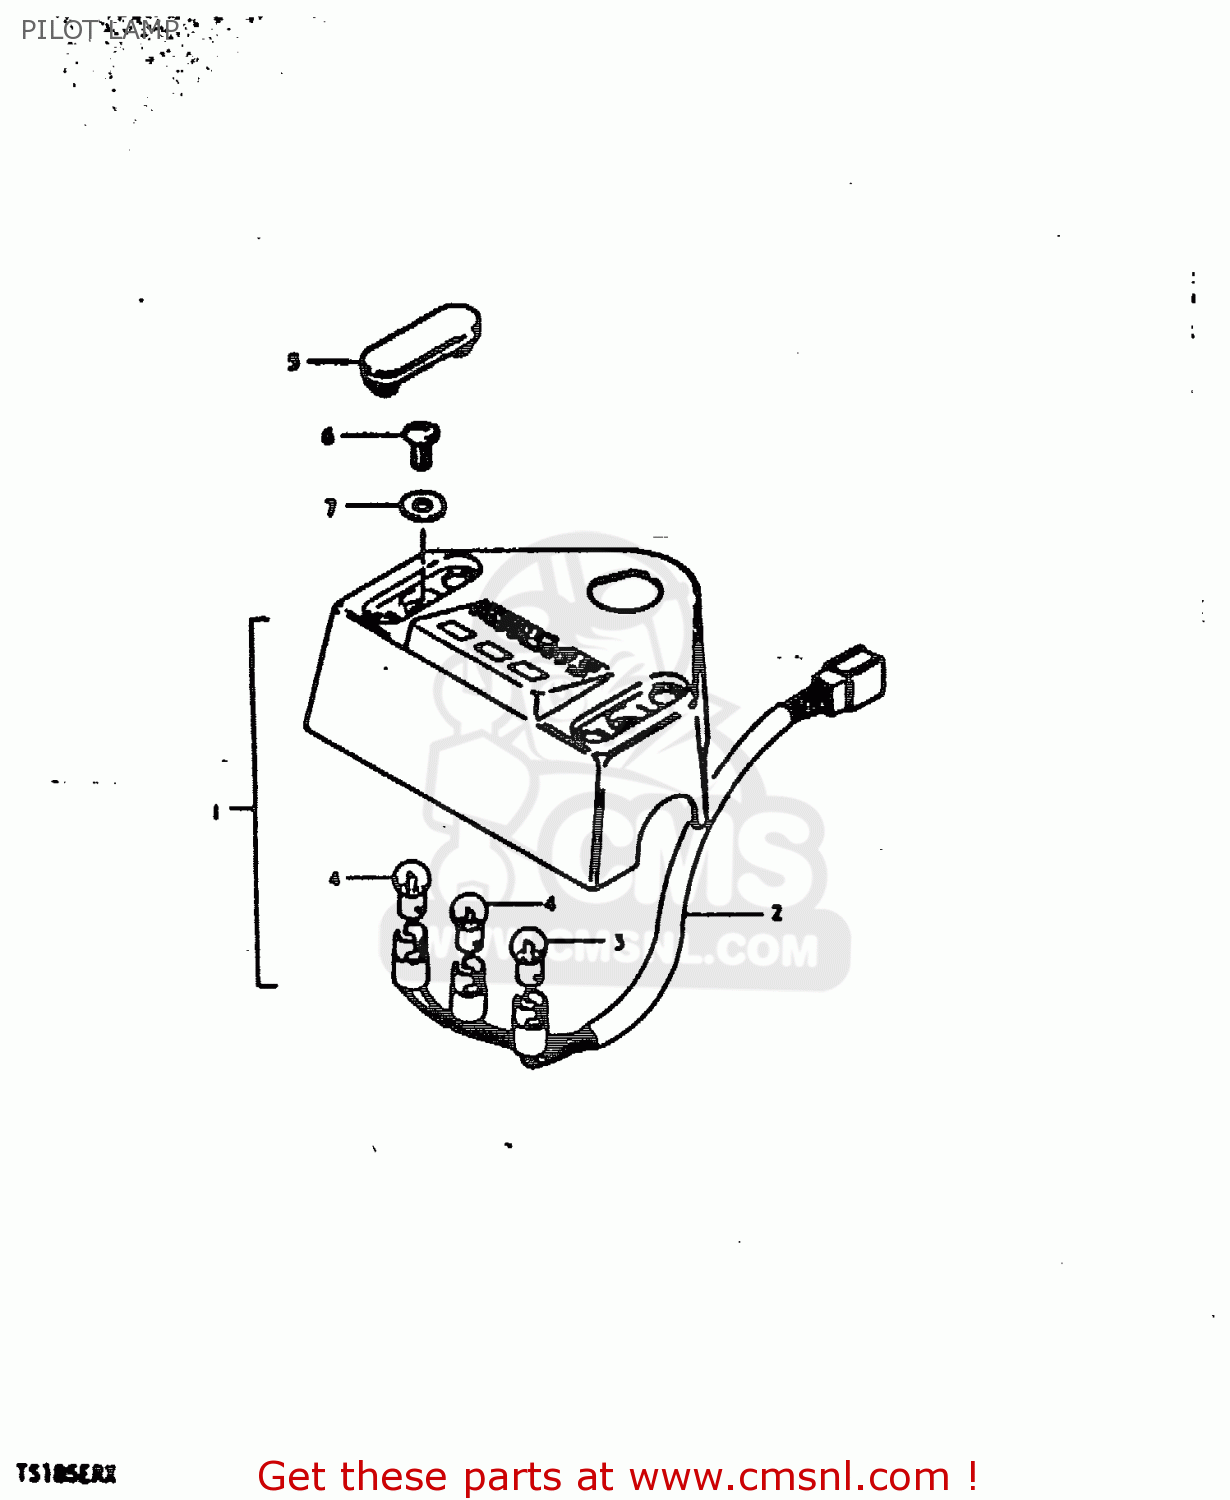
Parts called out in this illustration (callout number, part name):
1	CASE,PILOT BULB
2	SOCKET
3	BULB(6V1.7W,STANLEY,A61A)
4	BULB(6V/3W)
5	CAP,PILOT BOX BOLT
6	SCREW 6X12
7	WASHER
